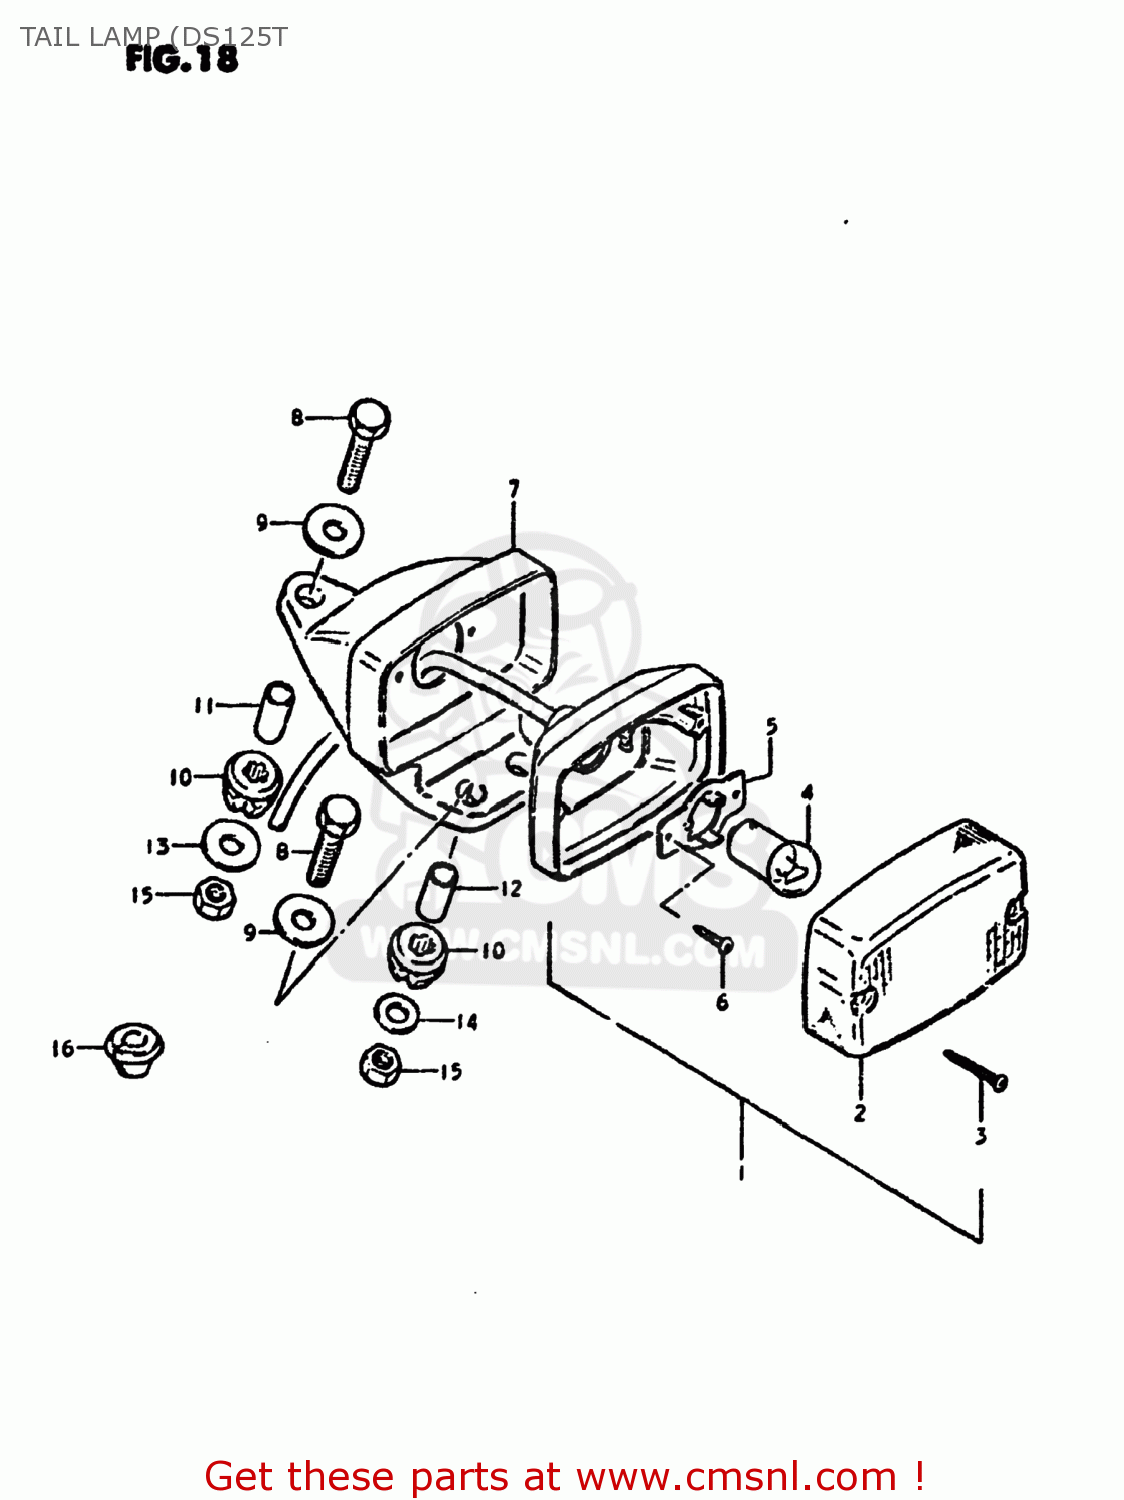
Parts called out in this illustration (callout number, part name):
1	LAMP UNIT,TAIL
2	LENS
3	SCREW
4	BULB(6V5W,TOKAI DENSO)
5	PLATE,TURN SIGNAL
6	SCREW
7	BRACKET
8	BOLT
9	WASHER (6.5X20X1.2)
10	CUSHION
11	SPACER
12	SPACER
13	WASHER
14	WASHER
15	NUT
16	GROMMET
